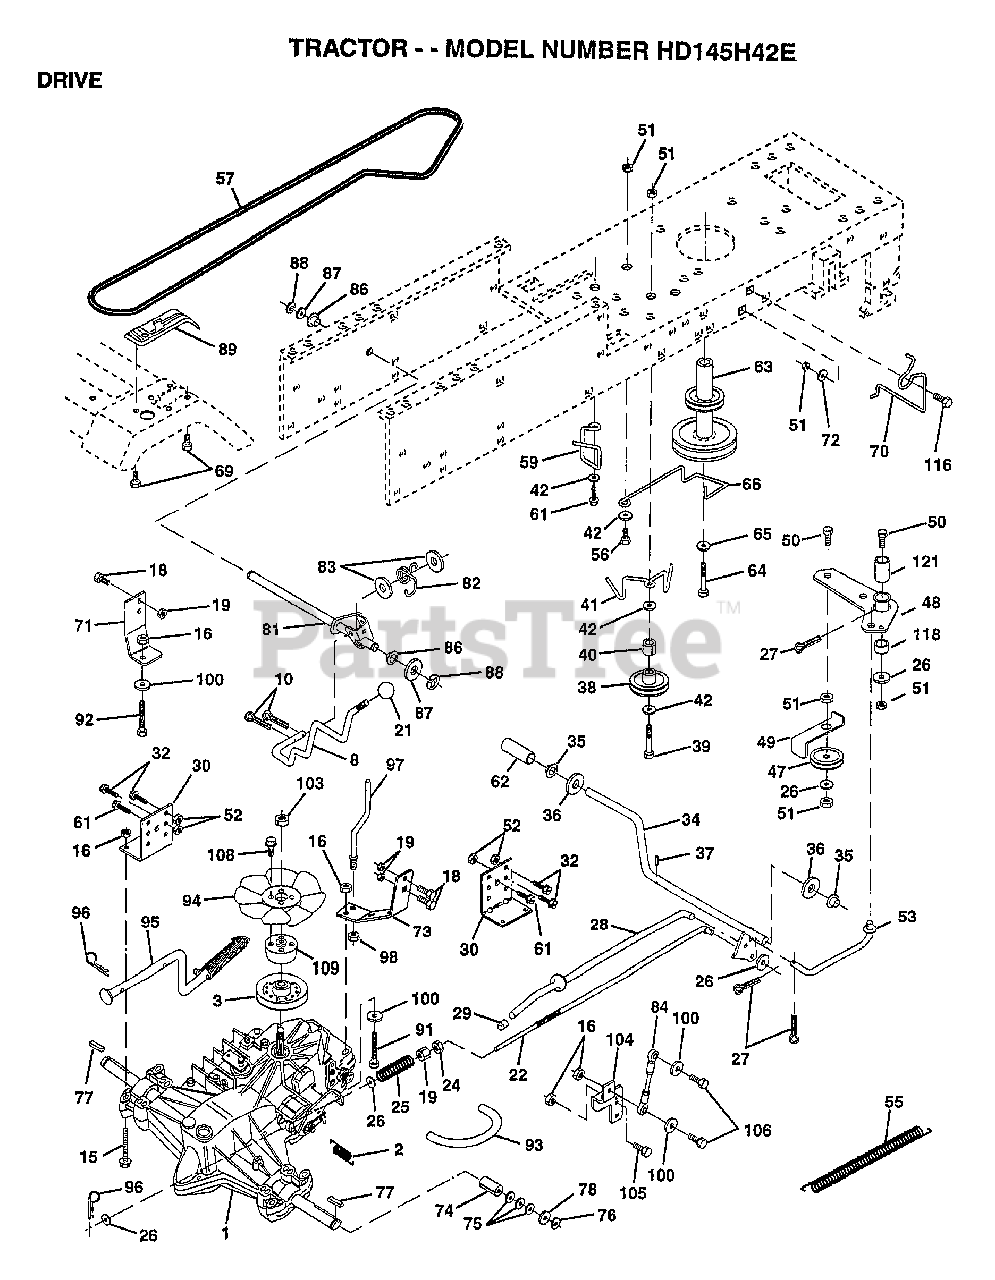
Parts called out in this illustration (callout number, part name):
1	TRANSAXLE HYD 0319-0500
2	SPRING RET BRAKE
3	PULLEY.4.20.HYDRO
8	ROD SHIFT FEND LT
10	PIN COTTER 1/8
15	BOLT.HX.FLG.5/16
16	NUT
18	BOLT
19	NUT
21	KNOB T (1/2-HOLE)
22	ROD.BRAKE.HYDRO.
24	NUT
25	SPRING ROD LT
26	WASHER
27	COTTER PIN
28	ROD.BRAKE.PARK.LT
29	PLUNGER CAP T
30	TRANSAXLE MTG BKT
32	BOLT
34	SHAFT ASM-PEDAL F
35	NYLON BEARING
36	WASHER LT
38	PULLEY.IDLER.FLAT
39	BOLT
40	SPACER T
42	WASHER
48	BELLCRANK ASM
49	RETAIN BELT
53	"LINK, CLUTCH T"
55	"SPRING, RETURN LT"
57	BELT-V.HYDR.84.61
59	KEEPER BELT CNTSP
61	SCREW
62	PEDAL COVER T
63	PULLEY.ENGINE
64	BOLT
65	LOCKWASHER
66	KEEPER-BELT
69	SCREW HEXWSH H-L
70	KEEPER BELT ENG
71	STRAP.TORQ.LH.HYD
72	WASHER
73	STRAP.TORQ.RH.HYD
74	SPACER SPLIT
75	WASHER
76	E-RING LT
77	SQUARE KEY
78	WASHER
81	SHAFT.CROS.500.HY
82	"SPRING,TORSION"
83	WASHER
84	ROD.TIE.BALL.HYD.
86	BUSHING
87	WASHER D
88	KLIP RING
92	HEX BOLT
93	"LINE FUEL HYD 4"""
94	"FAN 7"" HYDRO"
96	SPRING. RETAINER 1"
97	KEEPER.BELT.RH.HY
98	NUT
100	WASHER M
104	ARM.CONTROL.PUMP
105	SCREW CAP 5/16-18
106	BOLT
108	SCREW.HXHD.10-20
109	ADAPTOR.FAN.HYDRO
116	BOLT RDHD 3/8-16
118	SPACER-BELLCRANK
121	NYLINER-CLUTCHING
